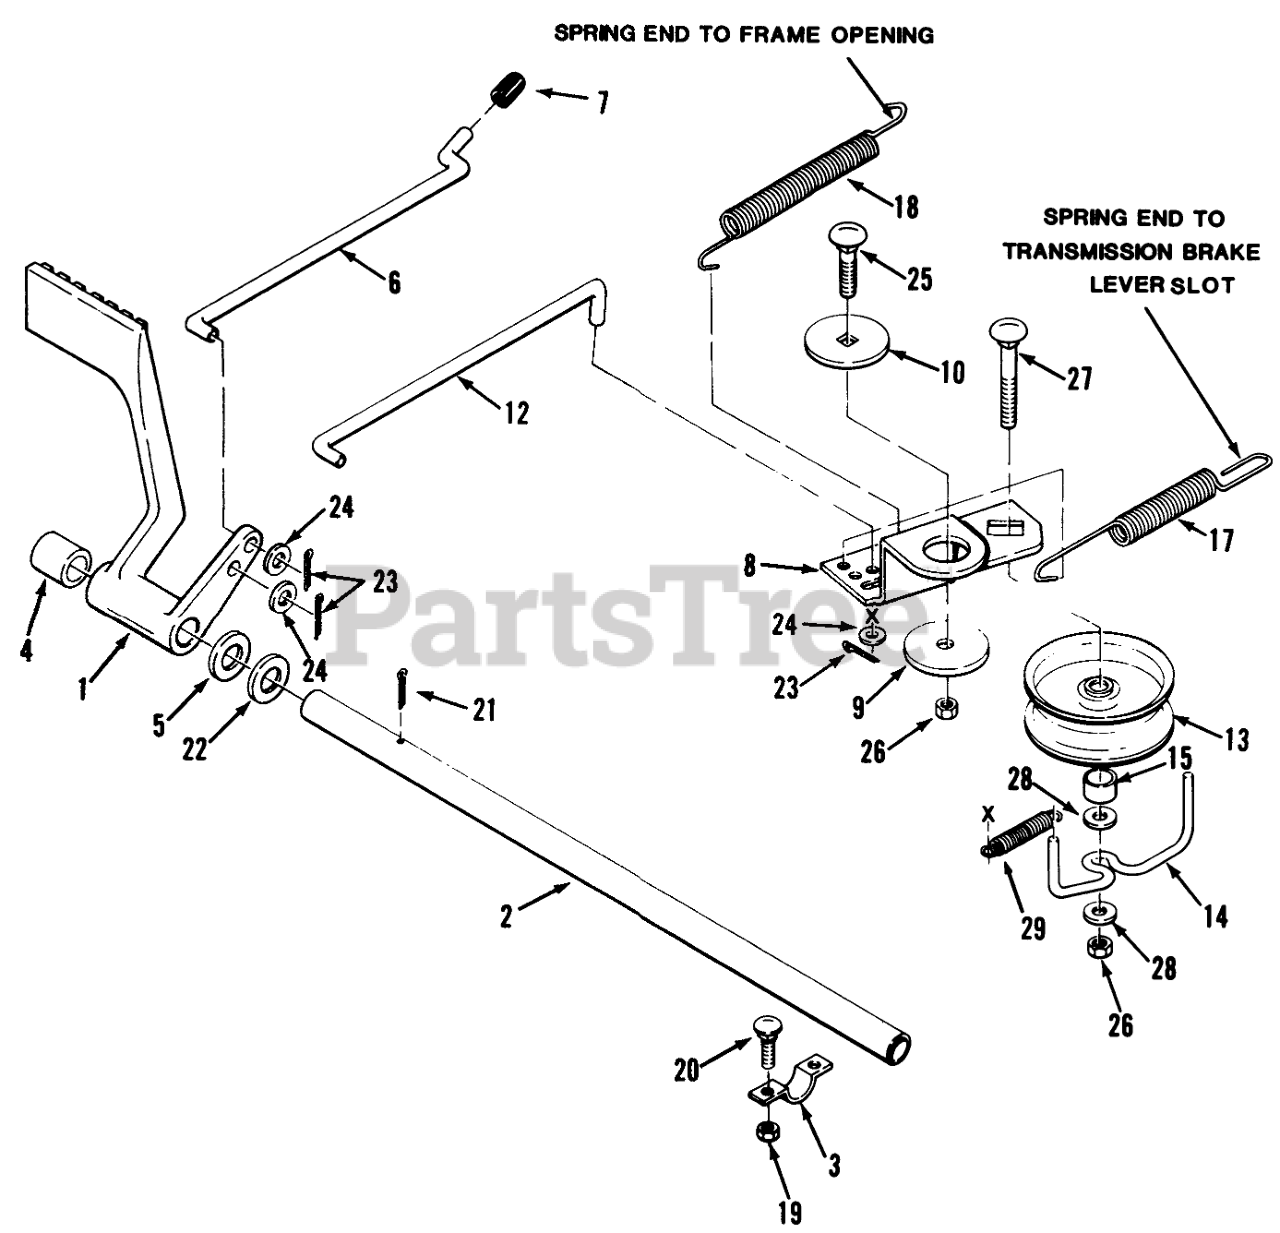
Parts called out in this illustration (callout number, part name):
1	PEDAL BRAKE R
2	SHAFT PEDAL
3	CLAMP
4	SPACER
5	WASHER-WAVE
6	Lock Rod
8	ARM-IDLER R
9	BUSHING
10	WASHER-BEARING
12	ROD-CLUTCH/BRAKE B
13	RETAINER R (NS)
14	GUIDE-BELT
15	SPACER
17	SPRING - BRAKE
18	SPRING - CLUTCH
19	Nut
20	Bolt
22	Washer
23	Cotter Pin
24	Washer
25	Bolt
26	NUT
27	Carriage Bolt 3/8-16 x 2-1/4
28	Washer
29	EXTENSION-SPRING
